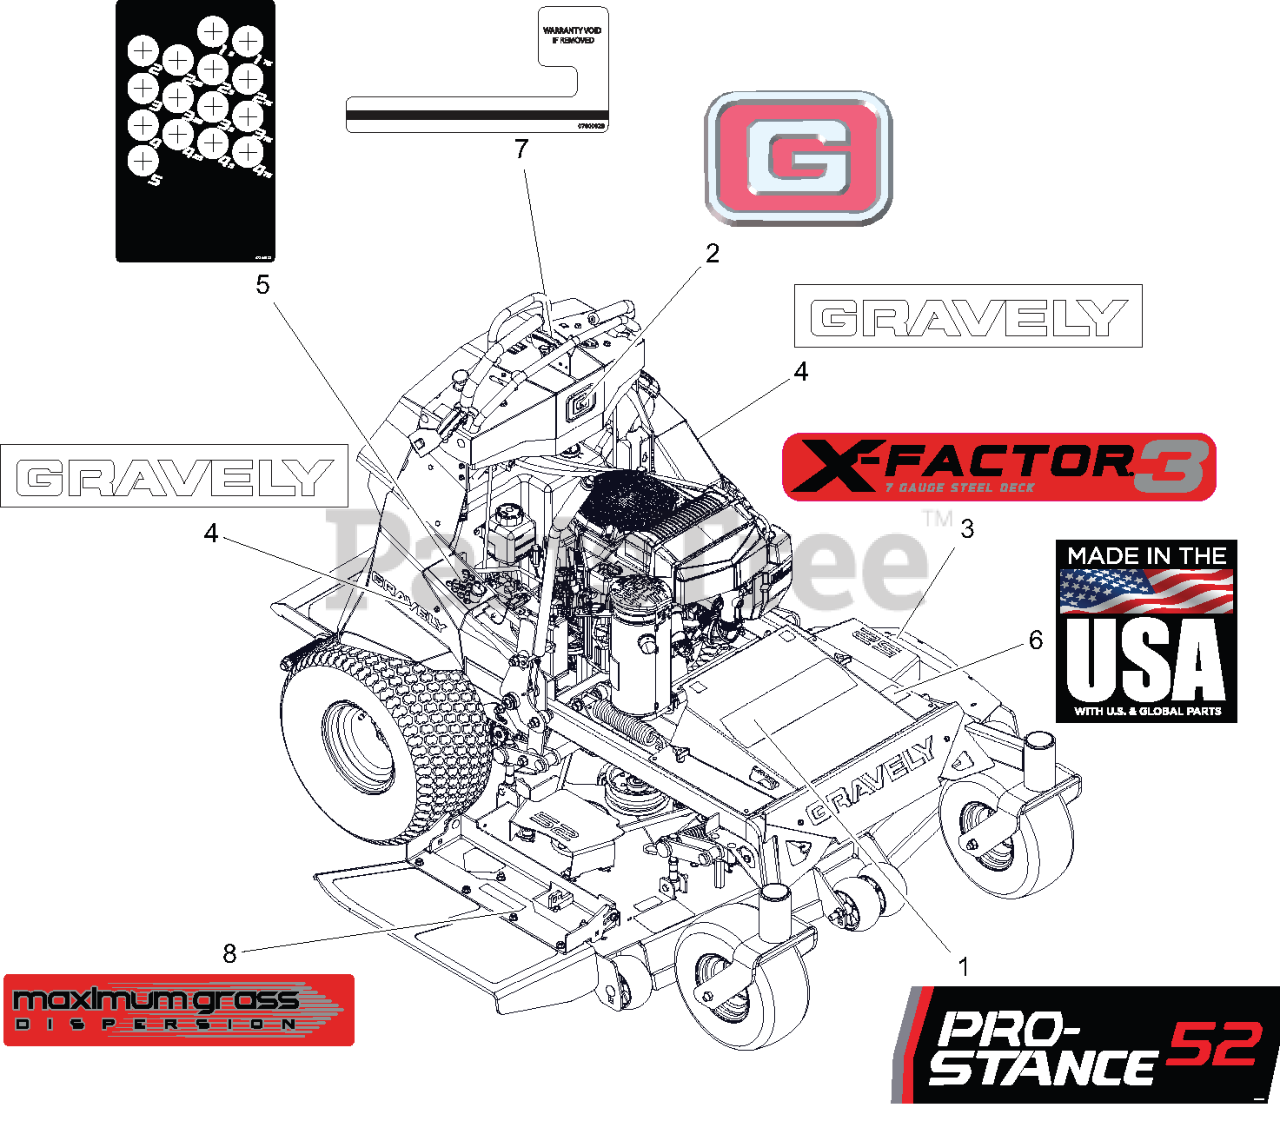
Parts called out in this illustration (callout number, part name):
1	DECAL, PROSTANCE 52
2	DECAL, GRAVELY BRAND
3	DECAL, DECK - X-FACTOR 3
4	DECAL, 9.5" GRAVELY LOGO
5	DECAL, DECK - HEIGHT ADJUST
6	DECAL, MADE IN USA
7	DECAL,HOURMETER - SECURITY
8	DECAL, DECK - MAX GRASS
